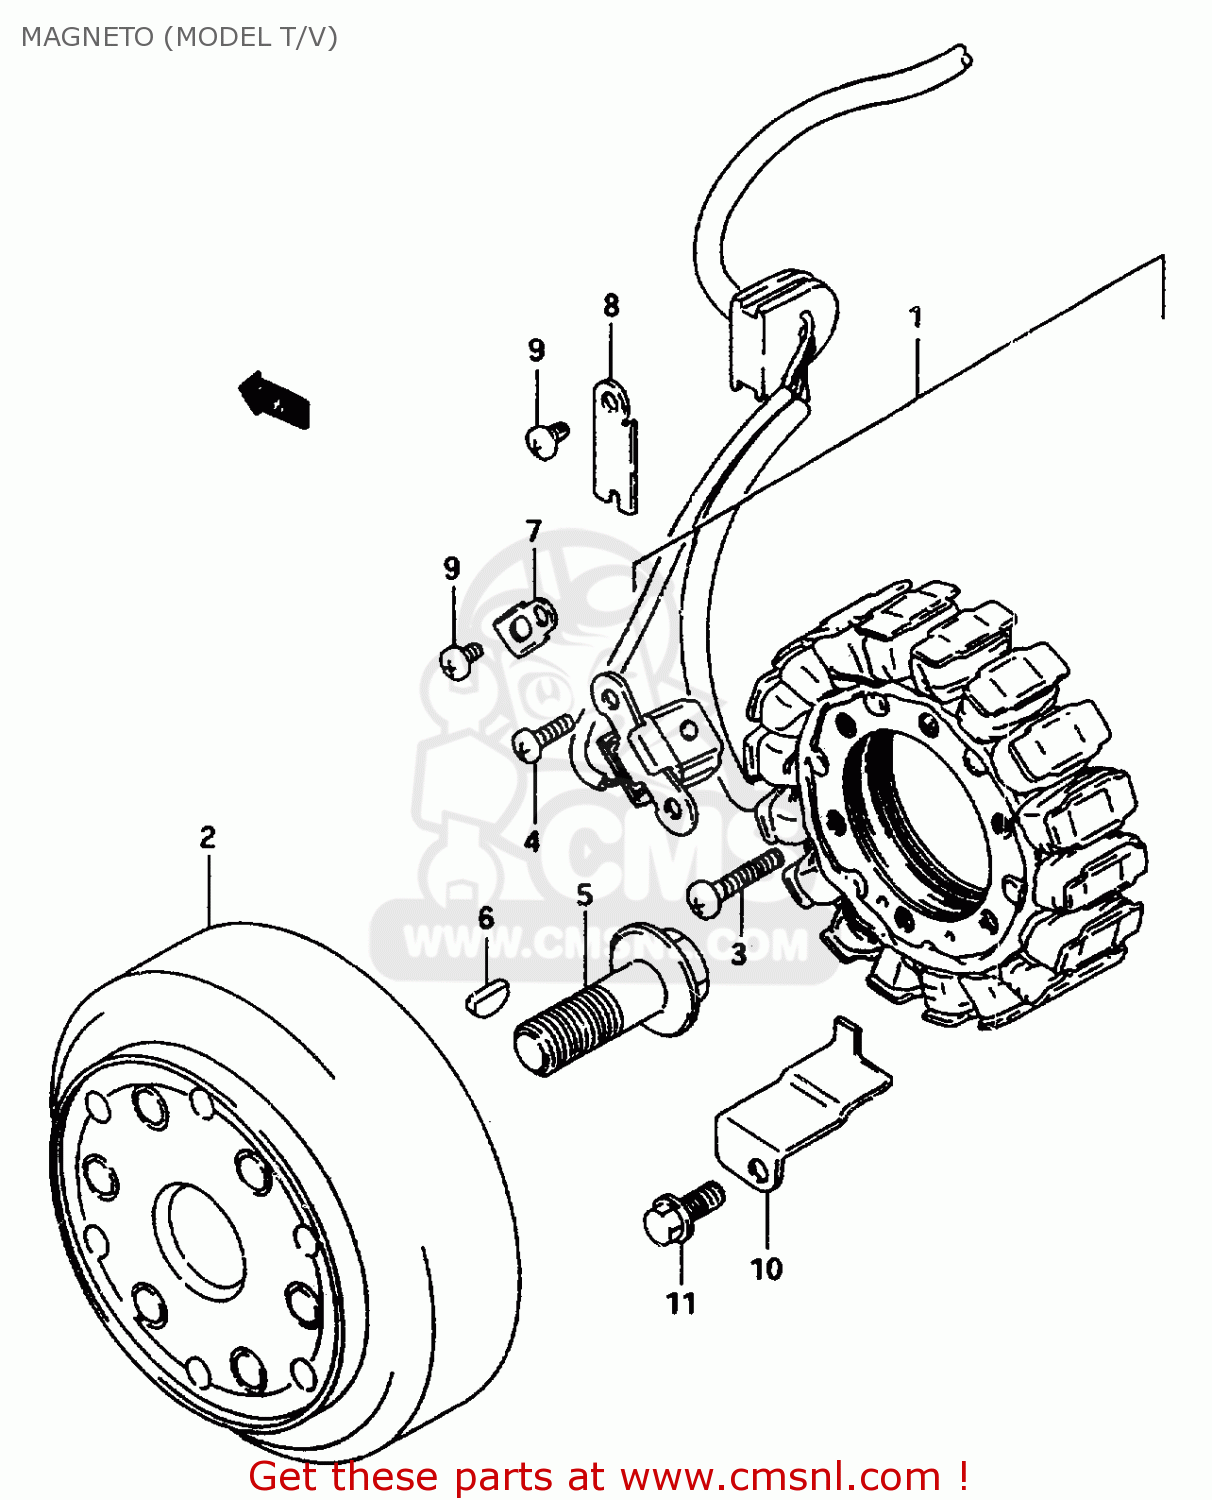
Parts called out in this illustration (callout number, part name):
1	STARTER ASSY
2	ROTOR ASSY
3	BOLT,G/S SWITC
4	SCREW
5	BOLT(14X43)
6	KEY
7	CLAMP,GENERATOR LEAD WIRE
8	CLAMP NO.1,MAGNETO READ WIRE
9	SCREW
10	CLAMP,MAGNETO LEAD WIRE
11	BOLT
12	BOLT
